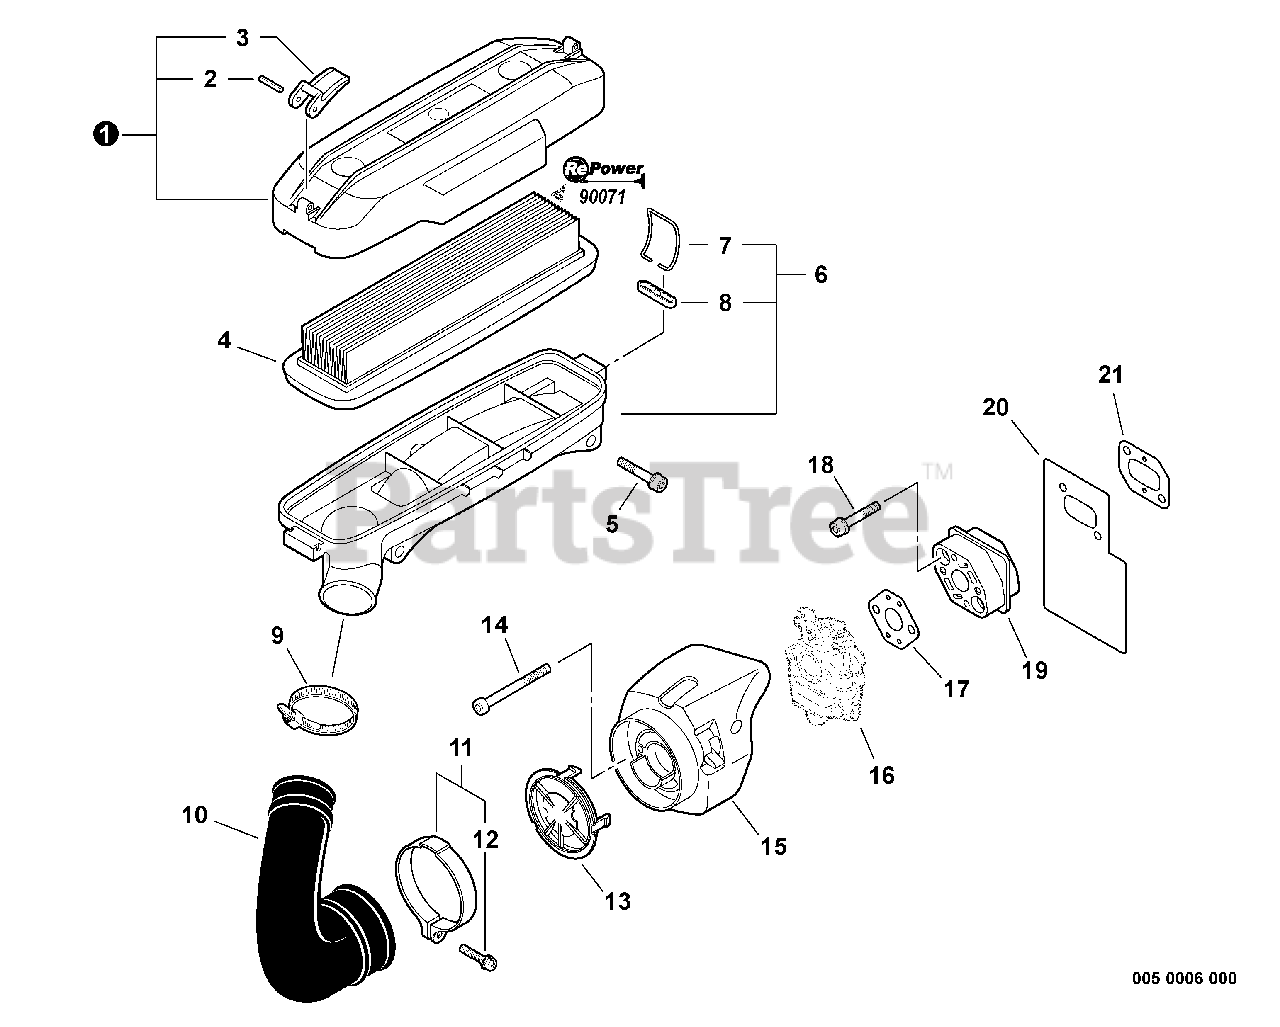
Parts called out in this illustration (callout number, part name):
1	COVER, AIR FILTER
2	PIN - SPRING -- 3X25
4	FILTER, AIR
5	SCREW - 5X35
6	AIR FILTER CASE ASSY
7	RING, RETAINING
8	RETAINER
9	CLAMP, HOSE
10	PIPE - INTAKE
11	CLAMP KIT
12	SCREW - 5X25
13	PLATE, PREVENT
14	SCREW - 5X55
15	AIR FILTER CASE ASSY
16	CARBURETOR
17	GASKET, INTAKE
18	SCREW - 5X25
19	INSULATOR, INTAKE
20	SHIELD, INTAKE
21	GASKET, INTAKE
22	RePower TUNE-UP KIT
